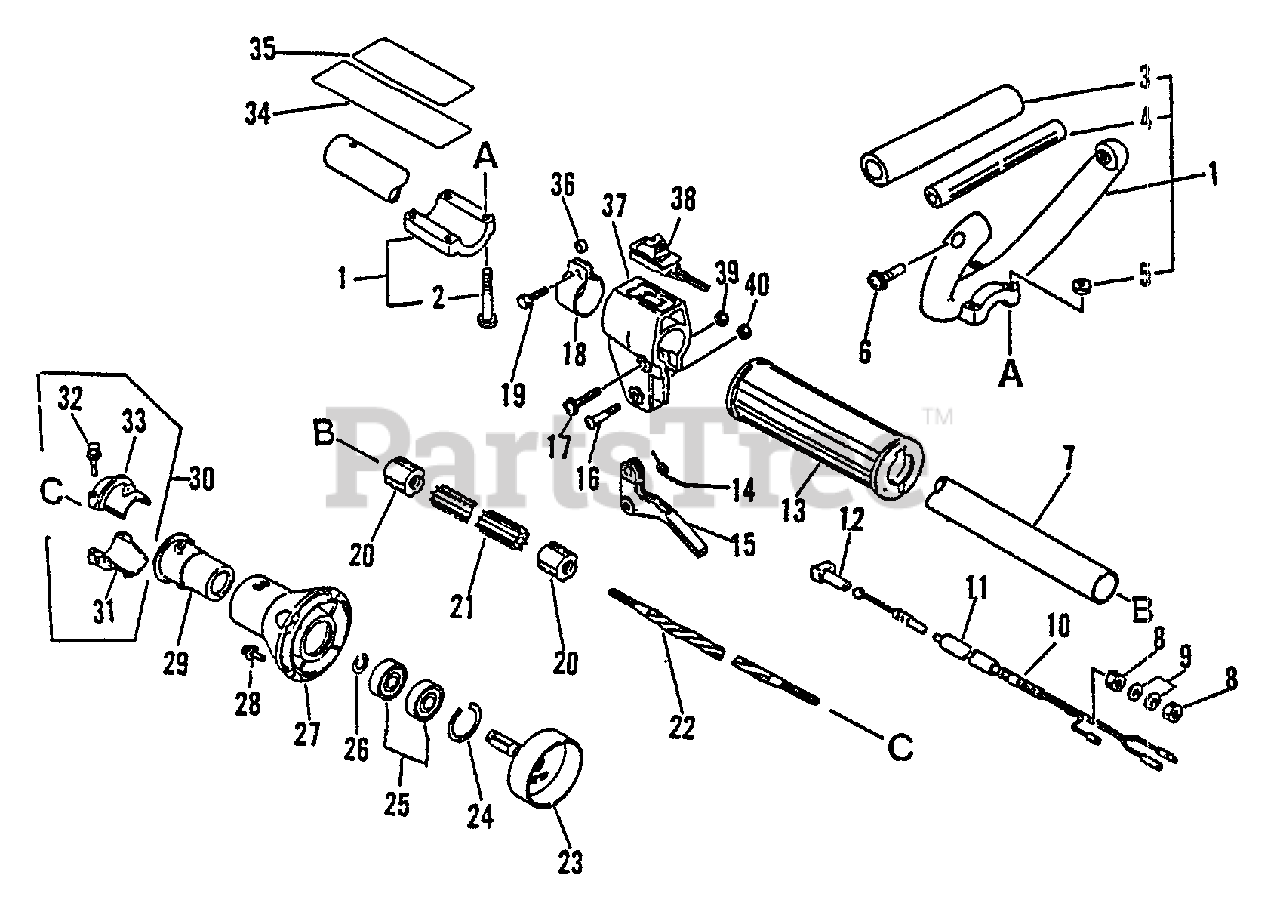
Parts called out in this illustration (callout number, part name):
1	LOOP HANDLE ASSY
2	SCREW 5×35
3	GRIP, HANDLE
5	NUT M5
6	SCREW 5×30
7	MAIN PIPE ASSY 25×1500
9	WASHER 6.5×11.5×0.8
10	CABLE, THROTTLE
11	TUBE - VINYL
12	GUIDE, CABLE
13	GRIP
14	SPRING, THROTTLE
15	TRIGGER, THROTTLE
17	SCREW 5×30
19	BOLT 5×18
21	LINER, FLEXIBLE 21.6×1420
22	DRIVESHAFT - FLEXIBLE L= 1522
23	DRUM, CLUTCH
24	RING, SNAP 28
25	BEARING, BALL 6001
26	RING, RETAINING - 12
27	FLANGE, DRIVESHAFT HOUSING
28	SCREW 5×16
30	HOLDER KIT
32	BOLT - 5×25
33	HOLDER, MAIN PIPE - UPPER
34	LABEL - CAUTION
35	LABEL, CAUTION
36	SPACER, GUARD
37	BRACKET, THROTTLE CONTROL
38	IGNITION SWITCH ASSY
39	NUT M5
40	NUT, LOCK M5
